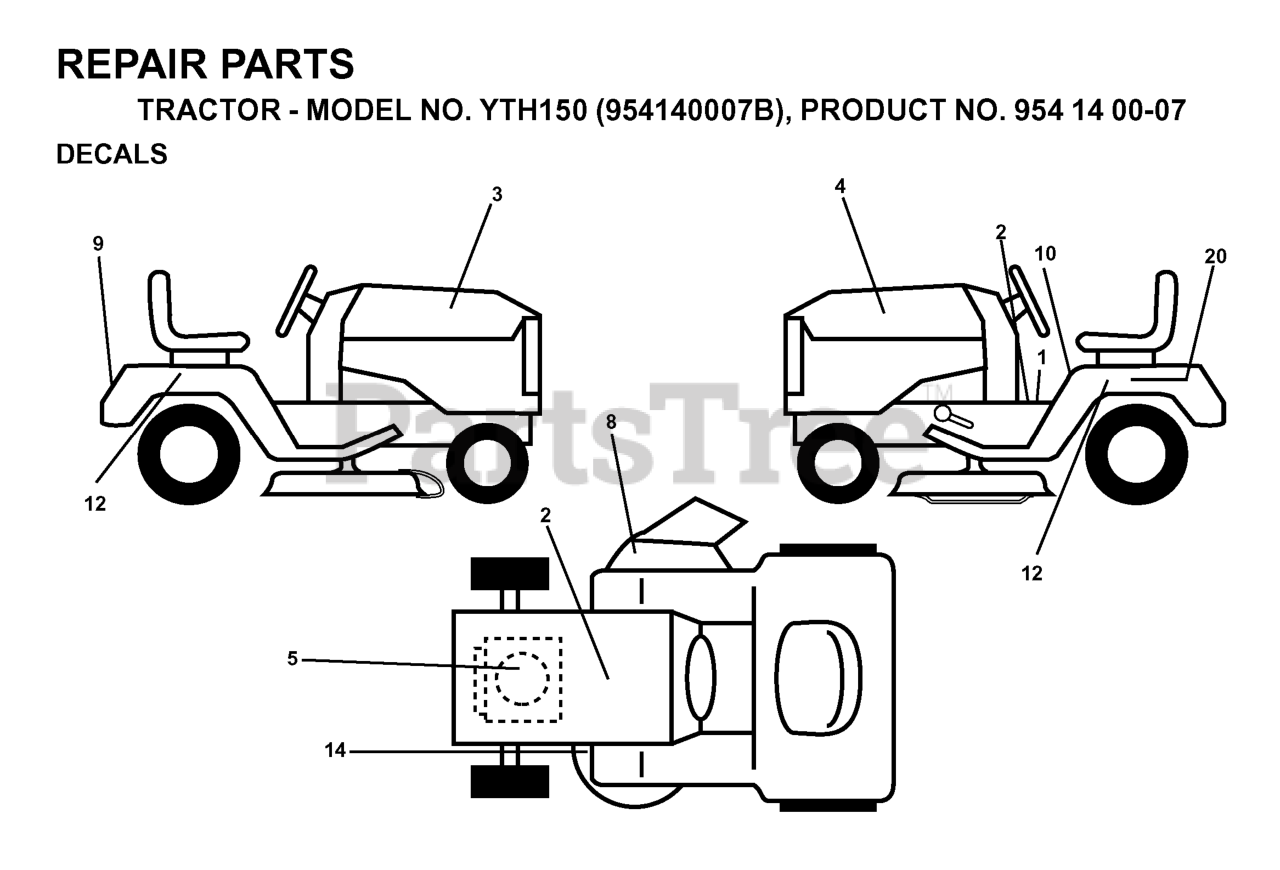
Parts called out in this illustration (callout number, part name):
2	DECAL BTRY SYMBOLS
3	DECAL, HOOD LH YTH150
4	DECAL, HOOD RH YTH150
8	DECAL WARNING (ENGLISH/FRENCH)
9	DECAL FENDER HUSQ
10	DECAL FENDER DANGER
14	DECAL V BELT SCHEMATIC
